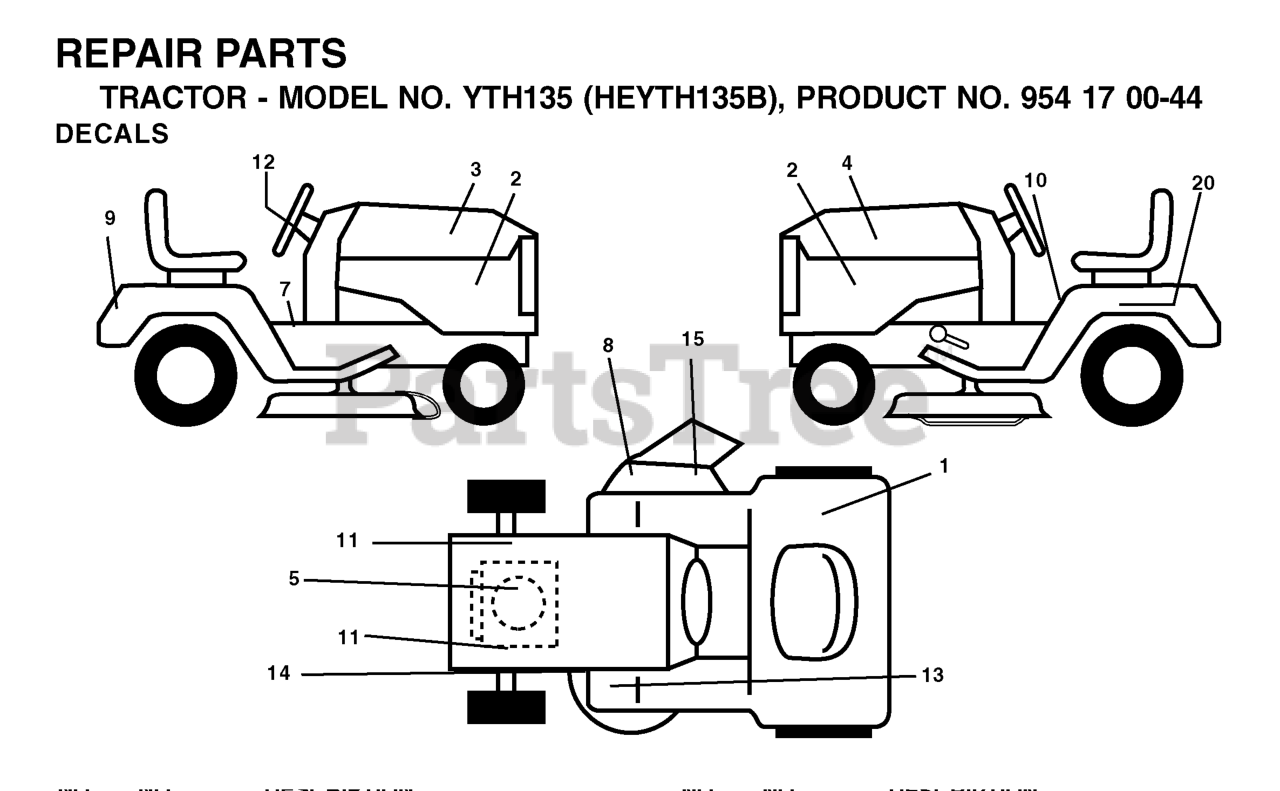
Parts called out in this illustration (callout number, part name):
1	Decal, Fender 100 DB/CE
2	DECAL PNL SIDE
7	DECAL PARK BRAKE
8	DECAL.INTERNATIONL.CUTFINGER
9	DECAL FENDER HUSQ
10	DECAL READ OWNER'S MAN SYMS
12	DECAL.WHEEL.STEERING.HUSQ.PERM
13	DECAL
14	DECAL V BELT SCHEMATIC
15	DECAL DECK "B" 42"
20	DECAL BTRY SYMBOLS
